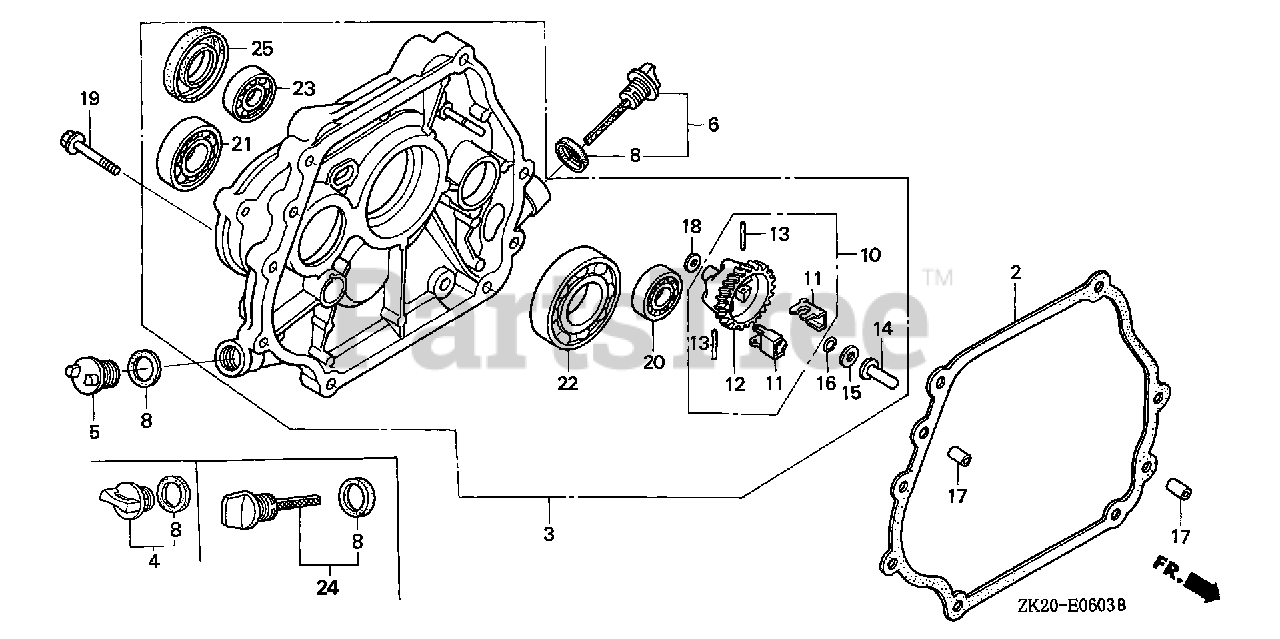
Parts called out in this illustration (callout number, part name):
2	GASKET, CASE COVER
3	COVER ASSY., CRANKCASE
4	CAP ASSY., OIL FILLER
6	CAP ASSY., OIL FILLER
8	GASKET, OIL FILLER CAP
10	GOVERNOR ASSY.
11	WEIGHT, GOVERNOR
12	HOLDER, GOVERNOR WEIGHT
13	PIN, GOVERNOR WEIGHT
14	SLIDER, GOVERNOR
16	CLIP, GOVERNOR HOLDER
17	PIN, DOWEL (8X12)
18	WASHER, PLAIN (6MM)
19	BOLT, FLANGE (8X35)
20	BEARING, RADIAL BALL (6202)
21	BEARING, RADIAL BALL (6204)
22	BEARING, RADIAL BALL (6206)
23	BEARING, RADIAL BALL (6302)
